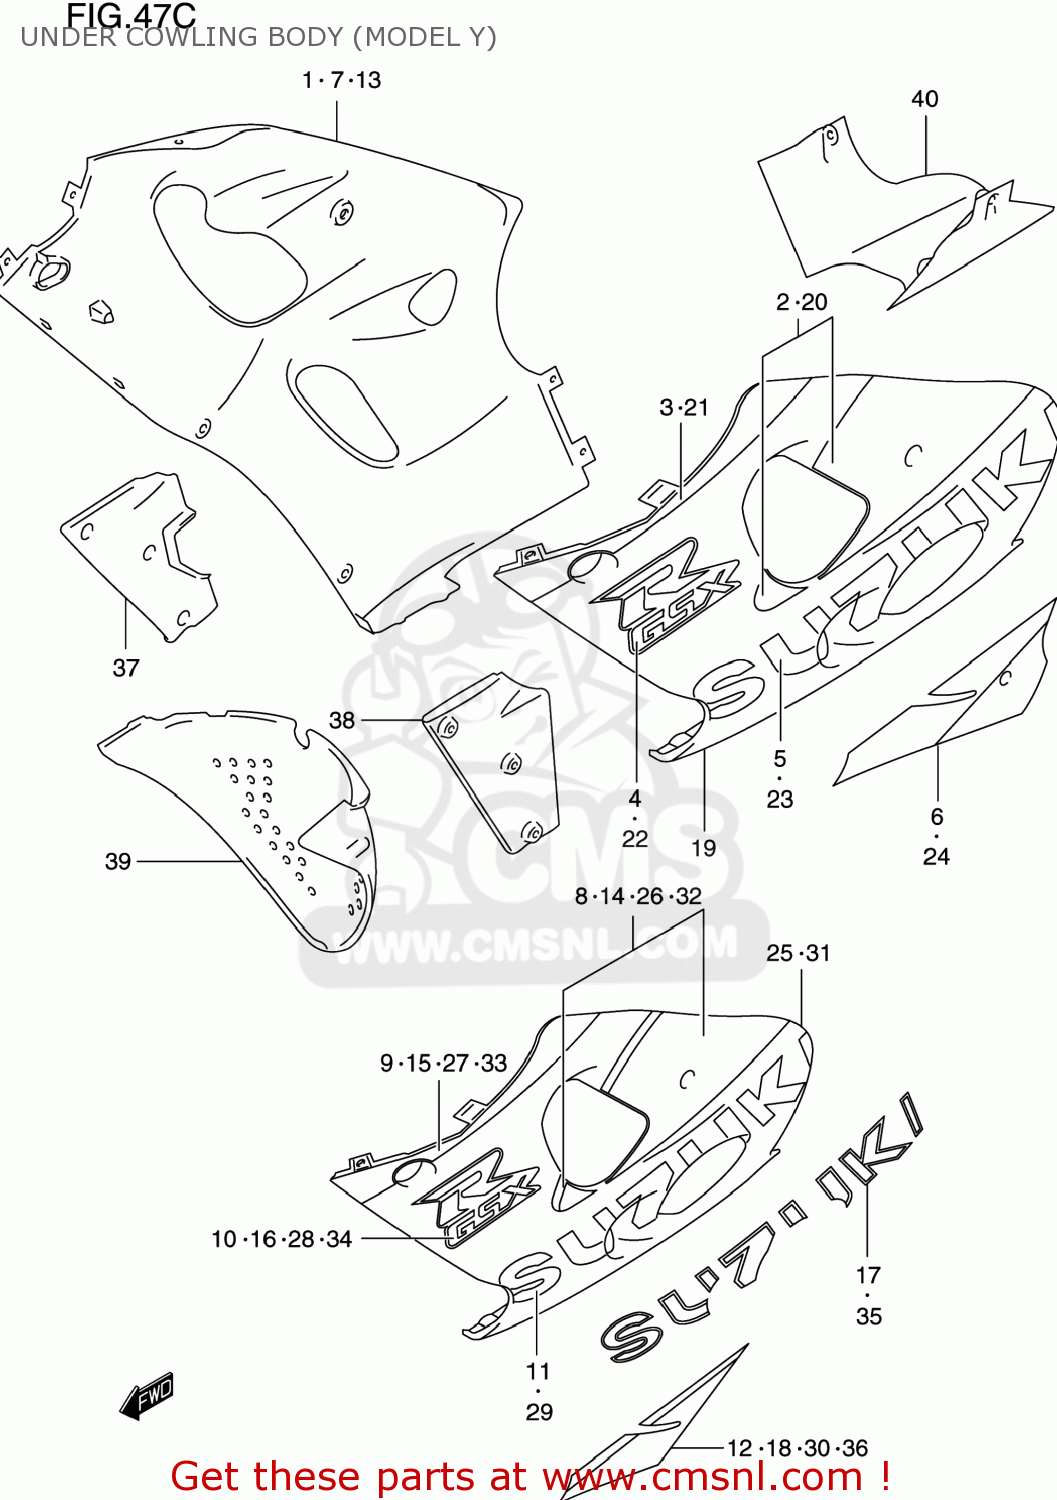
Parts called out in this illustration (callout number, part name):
1	COWLING ASSY,UNDER,R
2	TAPE SET,COWL UNDER,R(WHITE)
3	TAPE,UPR,R
4	EMBLEM,COWLING UNDER,GSXR
5	EMBLEM,COWLING UNDER,R
6	TAPE,COWL UNDER,R
7	COWLING ASSY,UNDER,R
8	TAPE SET,COWL UNDER,R
9	TAPE,COWL UNDER UPR,R
10	EMBLEM,COWLING UNDER,GSXR
11	EMBLEM,COWLING UNDER,R
12	TAPE,COWL UNDER,R
13	COWLING ASSY,UNDER,R
14	TAPE SET,UNDER,R
15	TAPE,UPR,R
16	EMBLEM,COWLING UNDER,GSXR
17	EMBLEM,SUZUKI,R
18	TAPE UNDER,RIGHT
19	COWLING ASSEMBLY,UNDER,LEFT
20	TAPE SET,COWL UNDER,L(WHITE)
21	TAPE,UPR,L
22	EMBLEM,COWLING UNDER,GSXR
23	EMBLEM,COWLING UNDER,L
24	TAPE,COWL UNDER,L
25	COWLING ASSY,UNDER,L
26	TAPE SET,COWL UNDER,L
27	TAPE,COWL UNDER UPR,L
28	EMBLEM,COWLING UNDER,GSXR
29	EMBLEM,COWLING UNDER,L
30	TAPE,COWLING,UNDER,LEFT
31	COWLING ASSY,UNDER,L
32	TAPE SET,UNDER,L
33	TAPE,UPR,L
34	EMBLEM,COWLING UNDER,GSXR
35	EMBLEM,SUZUKI,L
36	TAPE,UNDER,LEFT
37	COWLING,UNDER INNER,R
38	COWLING,UNDER INNER,L
39	COWLING,UNDER CTR
40	COWLING ASSEMBLY,UNDER,REAR
